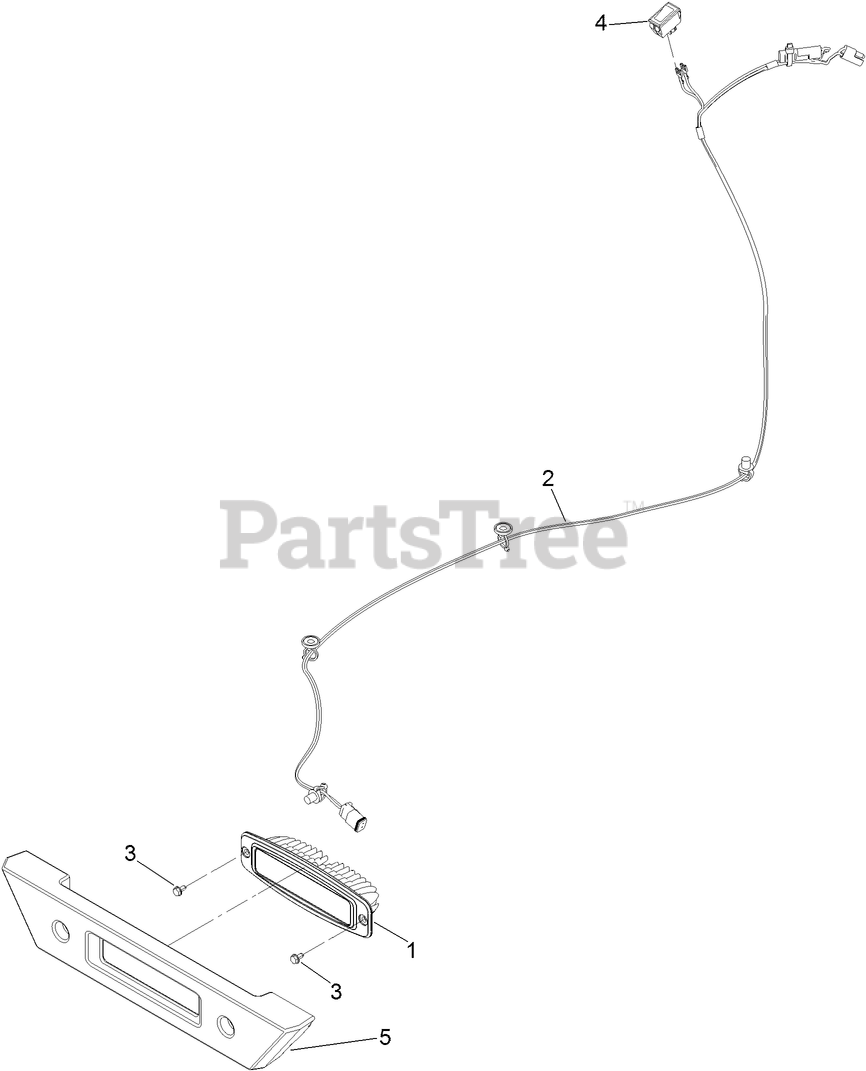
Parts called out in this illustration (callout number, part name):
1	MOUNT-FLUSH, LIGHT
2	HARNESS-WIRE, LIGHT KIT
3	SCREW-HWH
4	SWITCH-ROCKER
5	BUMPER-FRONT
